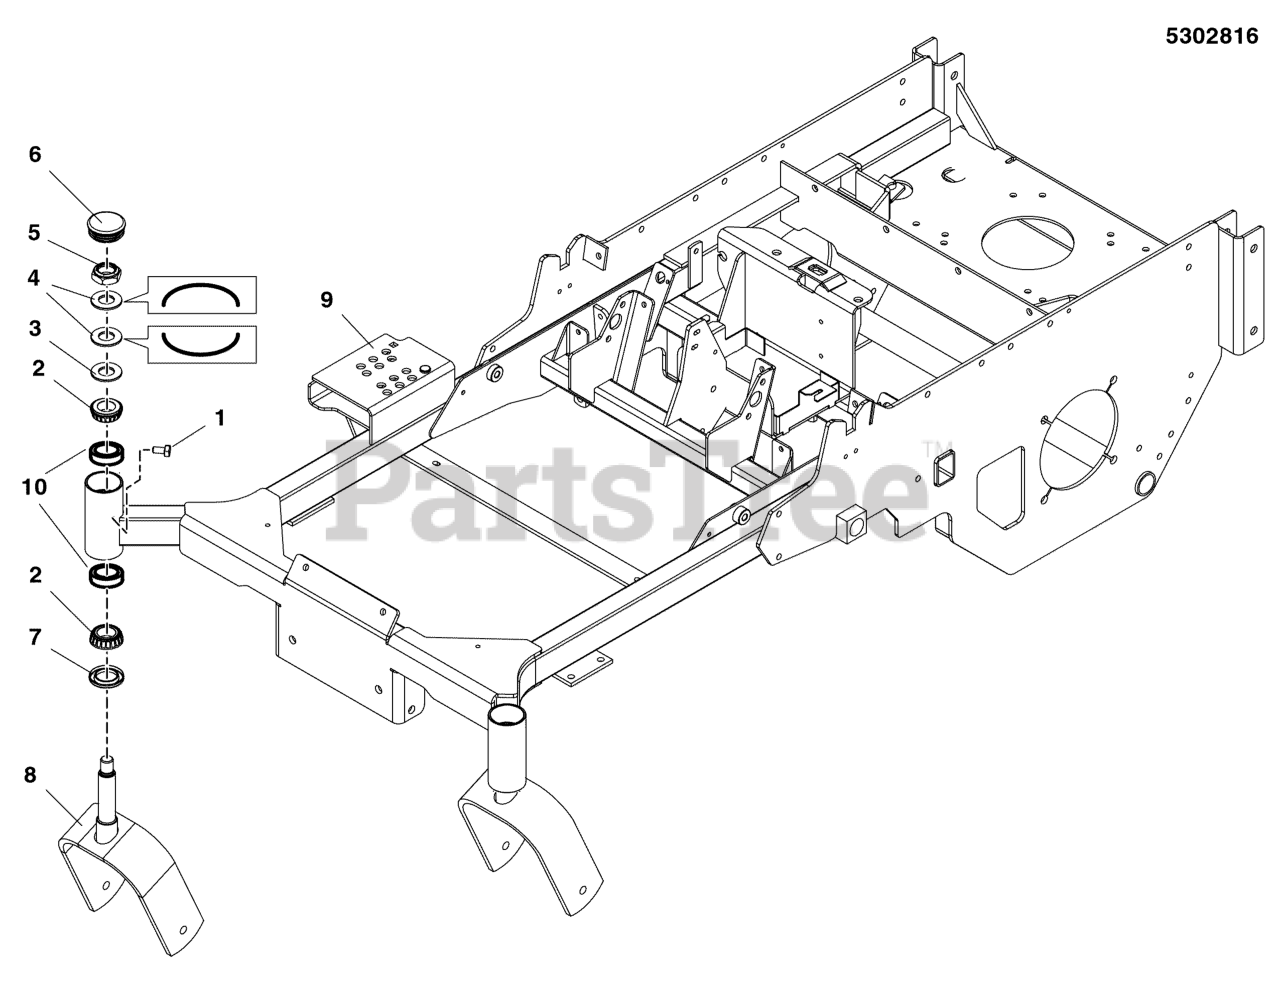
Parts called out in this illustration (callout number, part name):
1	BOLT, 1/4-28 X 1/2, GD5 YZ
2	BEARING, TAPERED ROLLER, 1
3	WASHER, 3/4 SAE
4	WASHER, BELLEVILLE - 1.500 X .755
5	NUT, 3/4-16, HEX JAM NYLON LOCK
6	CAP, GREASE, LOW PROFILE
7	SEAL, GREASE
8	WELD, CASTER YOKE - RED
9	WELD, MAIN FRAME, S150XT - RED
10	CUP, BEARING (SV)
